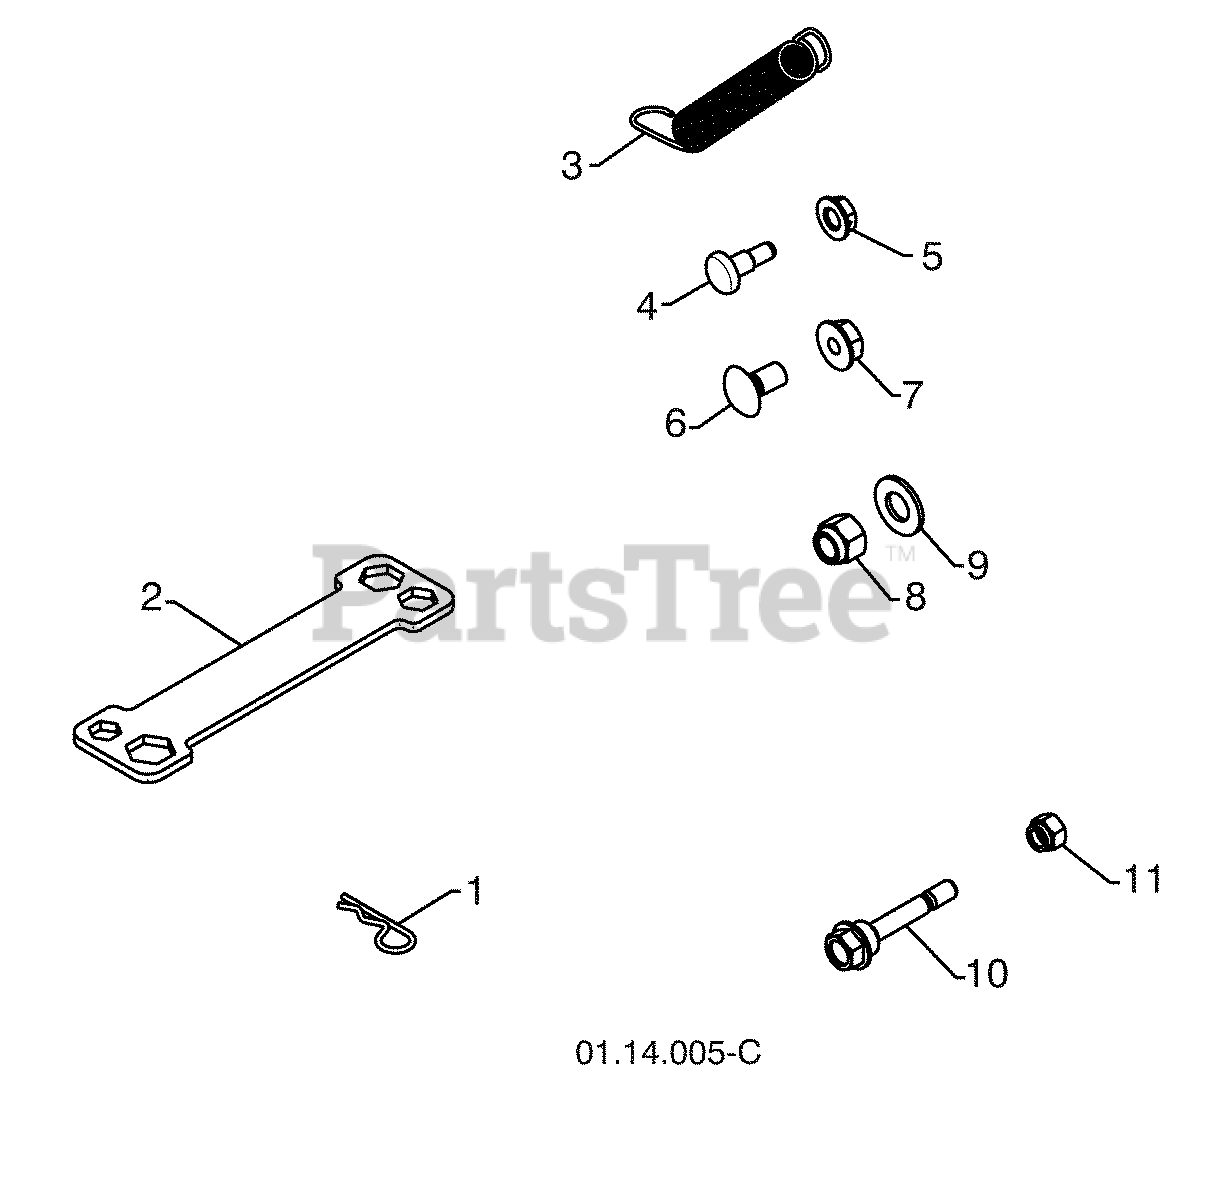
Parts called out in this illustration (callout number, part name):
1	RETAINER PIN
3	REMOTE SPRING
4	SHOULDER BOLT 1/4-20
5	LOCKNUT 1/4-20
6	CARRIAGE BOLT 5/16-18 X 5/8
7	LOCKNUT 5/16-18
8	LOCKNUT 3/8-16
9	WASHER 3/8
10	SHEAR BOLT 1/4-20 X 1-3/4
11	LOCKNUT 1/4-20
